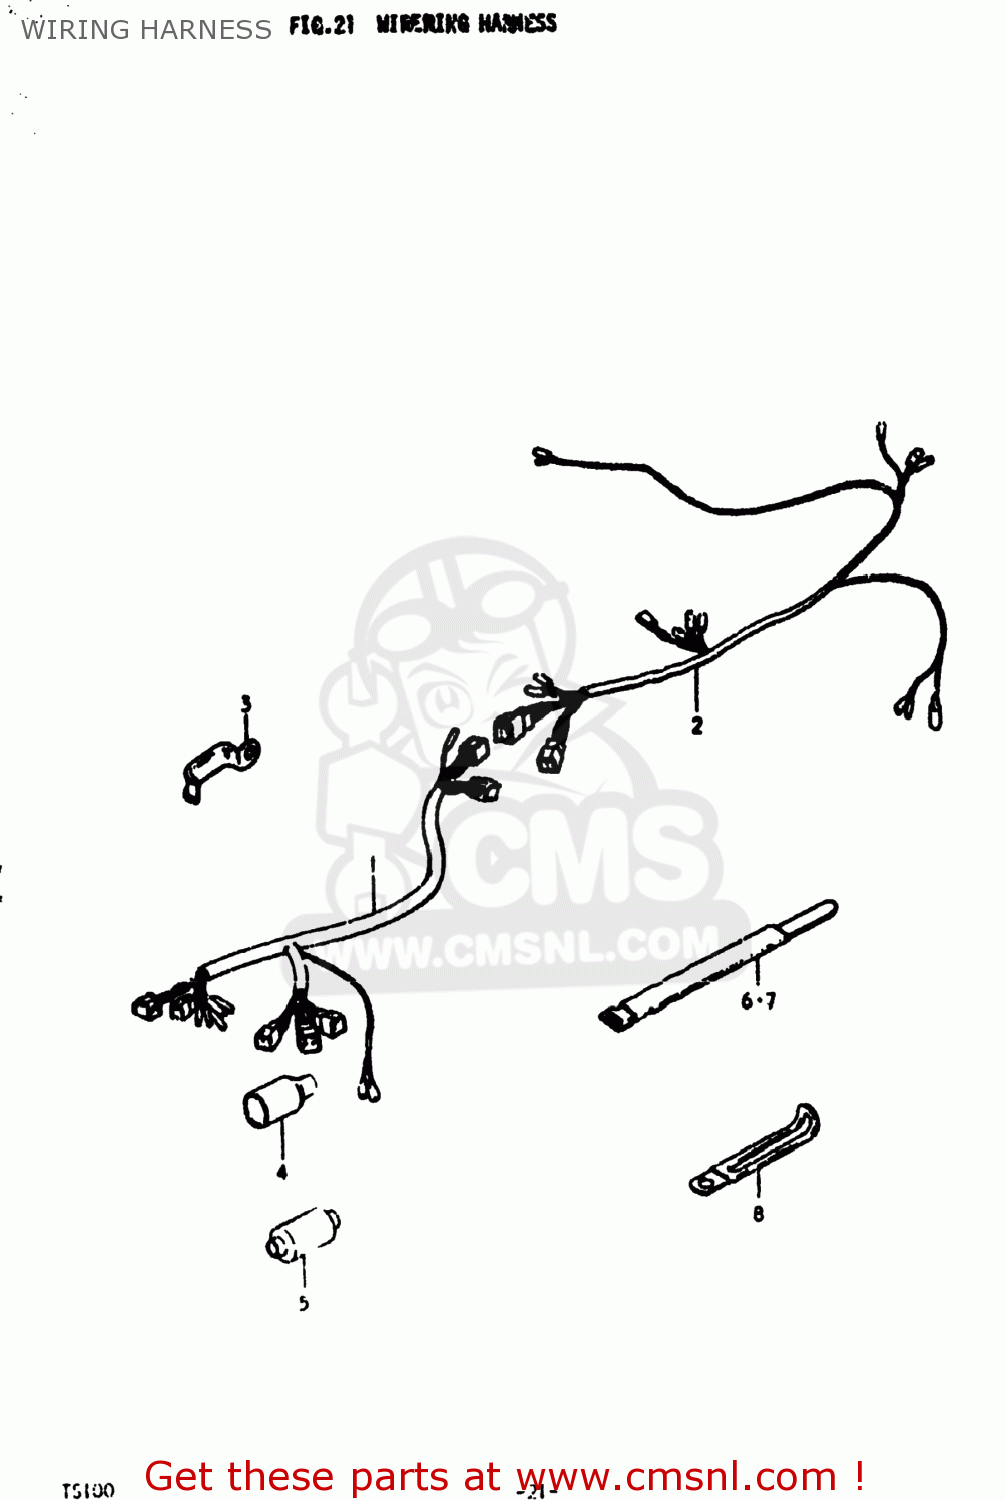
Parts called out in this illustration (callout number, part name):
1	HARNESS,WIRING
2	HARNESS,WIRING NO.2
3	CLAMP
4	BOOT,WIRING HARNESS
5	BOOT,WIRING HARNESS
6	CLAMP
7	CLAMP(L:250)
